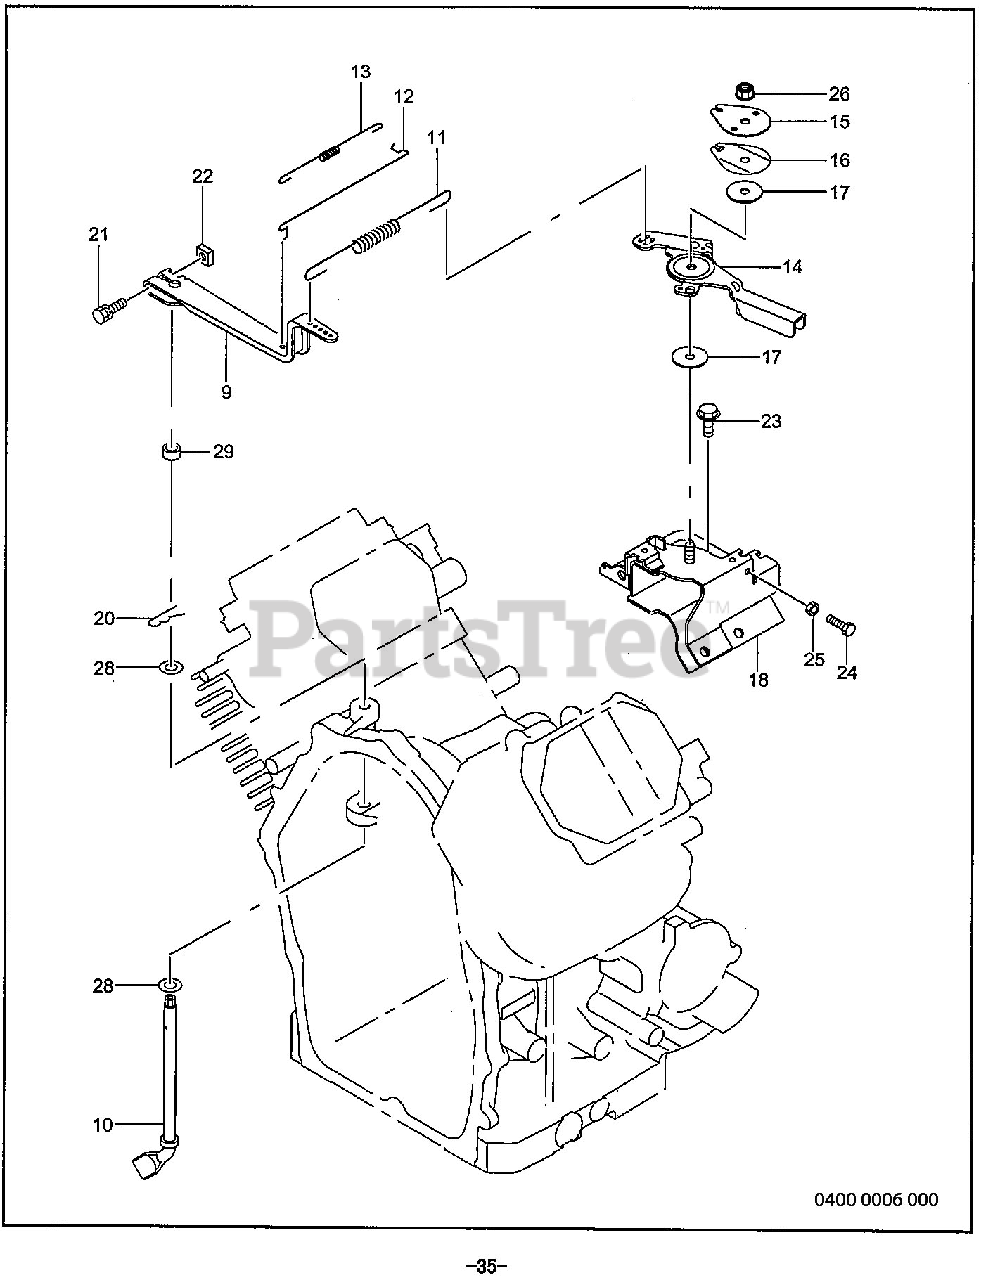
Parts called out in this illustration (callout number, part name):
9	GOVERNOR LEVER
9	GOVERNOR LEVER
10	GOVERNOR SHAFT
11	GOVERNOR SPRING
14	SPEED CONTROL LEVER
17	FRICTION WASHER
18	BRACKET UNIT, speed control
21	BOLT and WASHER ASSY
